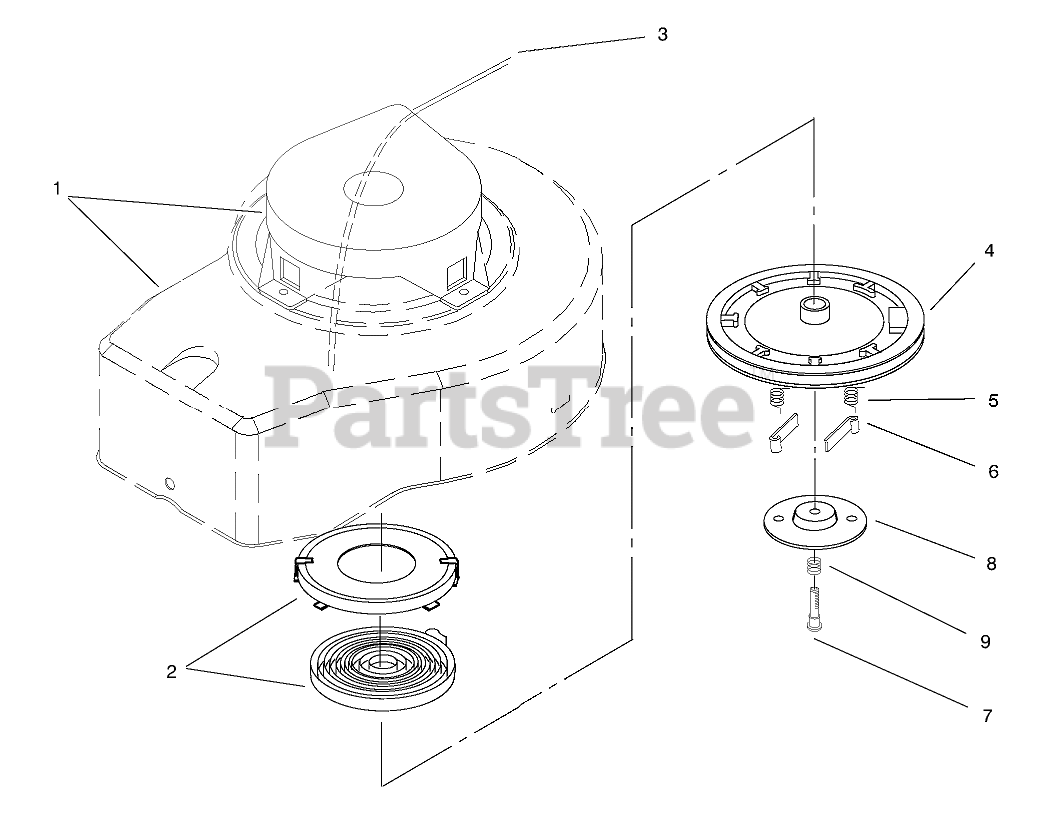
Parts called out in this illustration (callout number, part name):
1	HOUSING ASM
2	SPRING KEEPER ASM
3	ROPE - GREY 88 5/8
4	PULLEY ASSEMBLY
5	SPRING - DOG
7	SPRING - BRAKE
8	RETAINER
9	SCREW - CENTER
